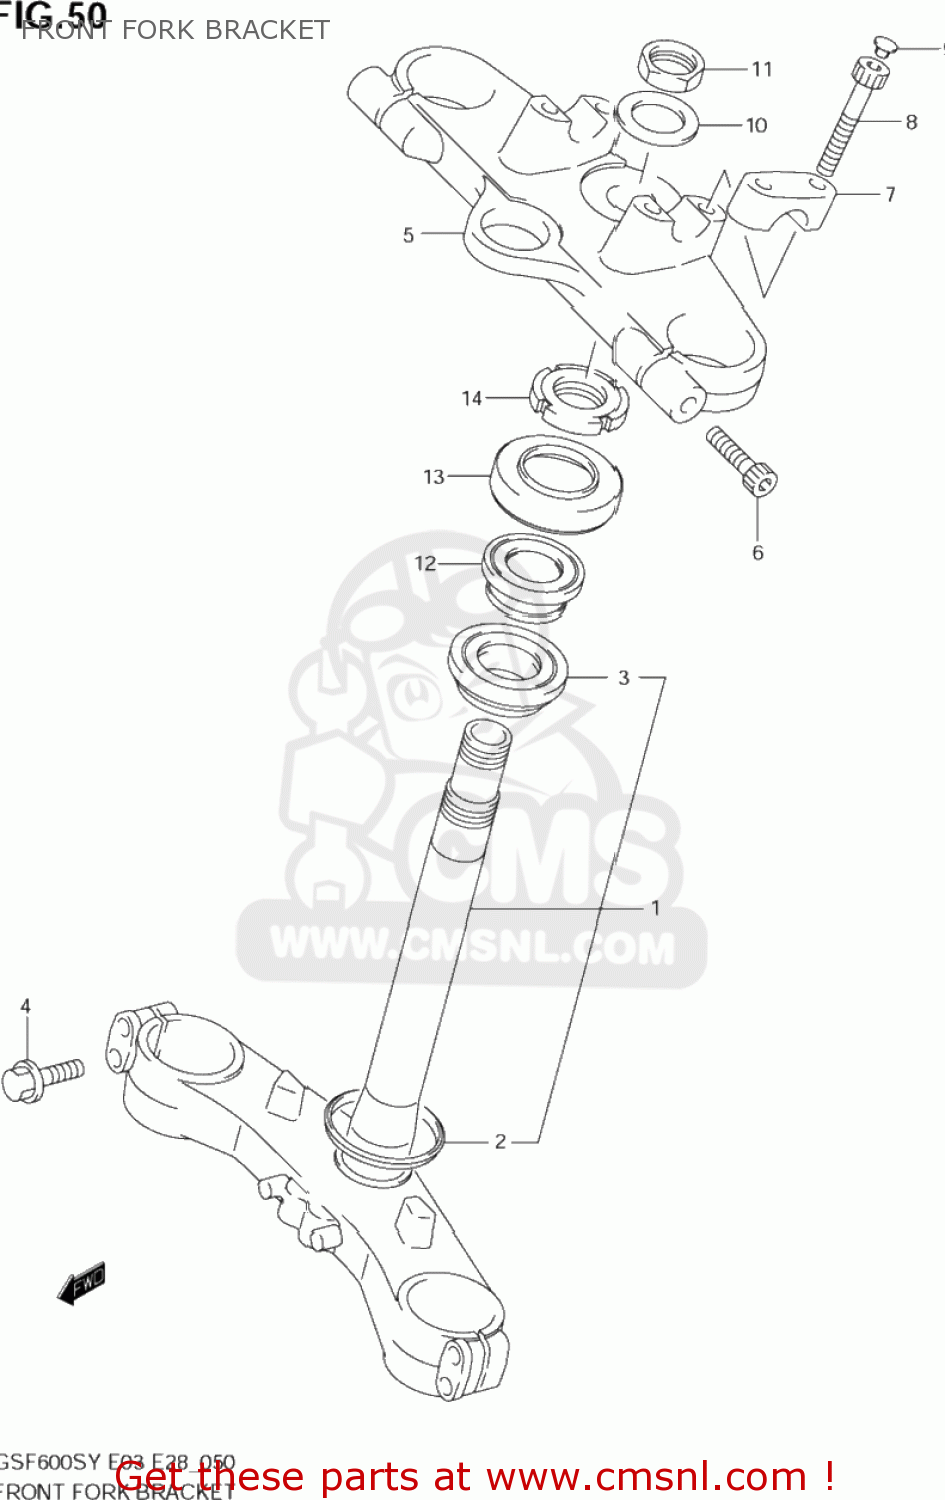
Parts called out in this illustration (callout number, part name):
1	BRACKET,UNDER
2	SEAL,STEERING LWR
3	BEARING(30X55X17)
4	BOLT
5	BRACKET,FR FORK UPR
6	BOLT
7	HOLDER,HANDLE
8	BOLT
9	CAP(OD:11)
10	WASHER(22.5X35.9X1.6)
11	NUT,CAP
12	BEARING(25X47X15)
13	DUST SEAL,STEERING UPR
14	NUT,STEERING STEM
